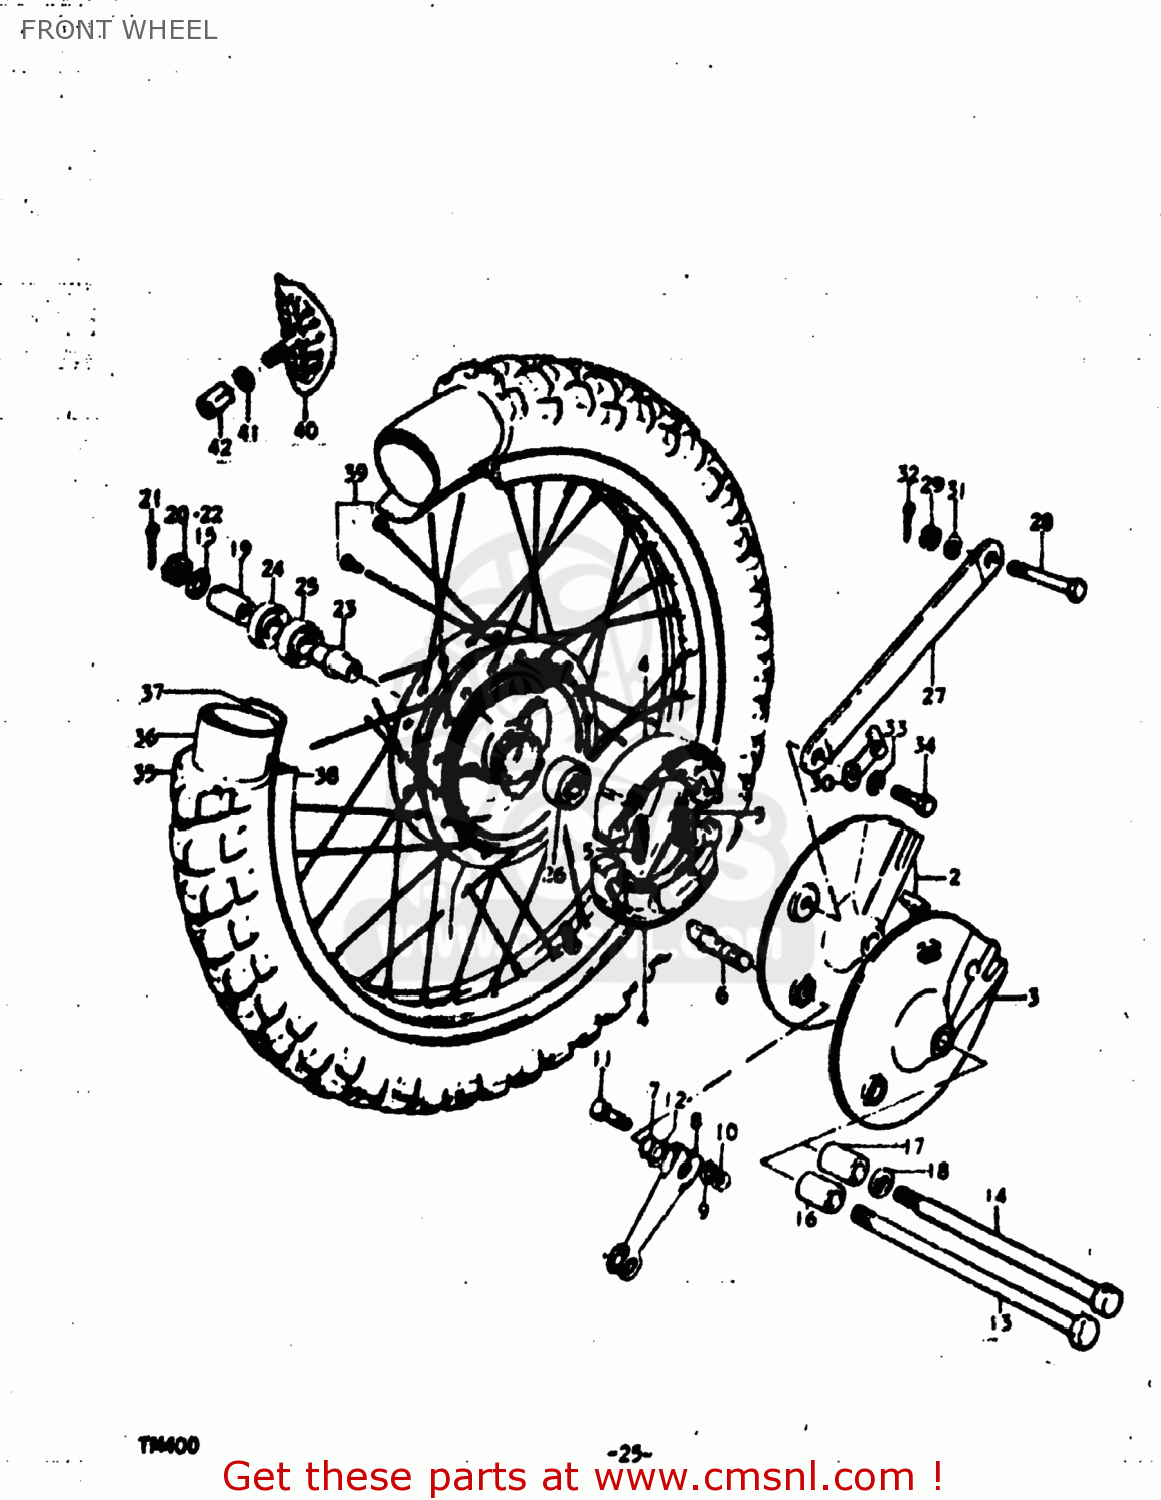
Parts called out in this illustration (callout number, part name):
1	HUB,FRONT
2	PANEL,FRONT HUB
3	PANEL,FRONT HUB
4	SHOE,BRAKE
5	SPRING(L:34)
6	CAM,FRONT BRAKE
7	O RING(D:2.5,ID:11.4)
8	LEVER,FRONT BRAKE CAM
9	WASHER
10	NUT
11	BOLT
12	WASHER(12.5X20X1)
13	AXLE,FRONT
14	AXLE,FRONT
15	WASHER
16	NUT,FRONT AXLE
17	SPACER(12X20X34.5)
18	SPACER
19	SPACER,FRONT AXLE,RIGHT
20	NUT (12MM)
21	COTTER PIN
22	NUT 12MM
23	SPACER,FRONT HUB BEARING
24	OIL SEAL(17X38X5)
25	BEARING
26	BEARING, RH
27	LINK, FRONT TORQUE
28	BOLT
29	NUT 8MM
30	MUD FLAP,FRONT FENDER,LEFT
31	WASHER
32	CLIP
33	LOCK WASHER
34	BOLT
35	TIRE,FRONT
36	TUBE
37	PROTECTOR,WHEEL,INNER
38	RIM,FRONT WHEEL
39	SPOKE SET
40	STOPPER,BEAD
41	WASHER
42	NUT
